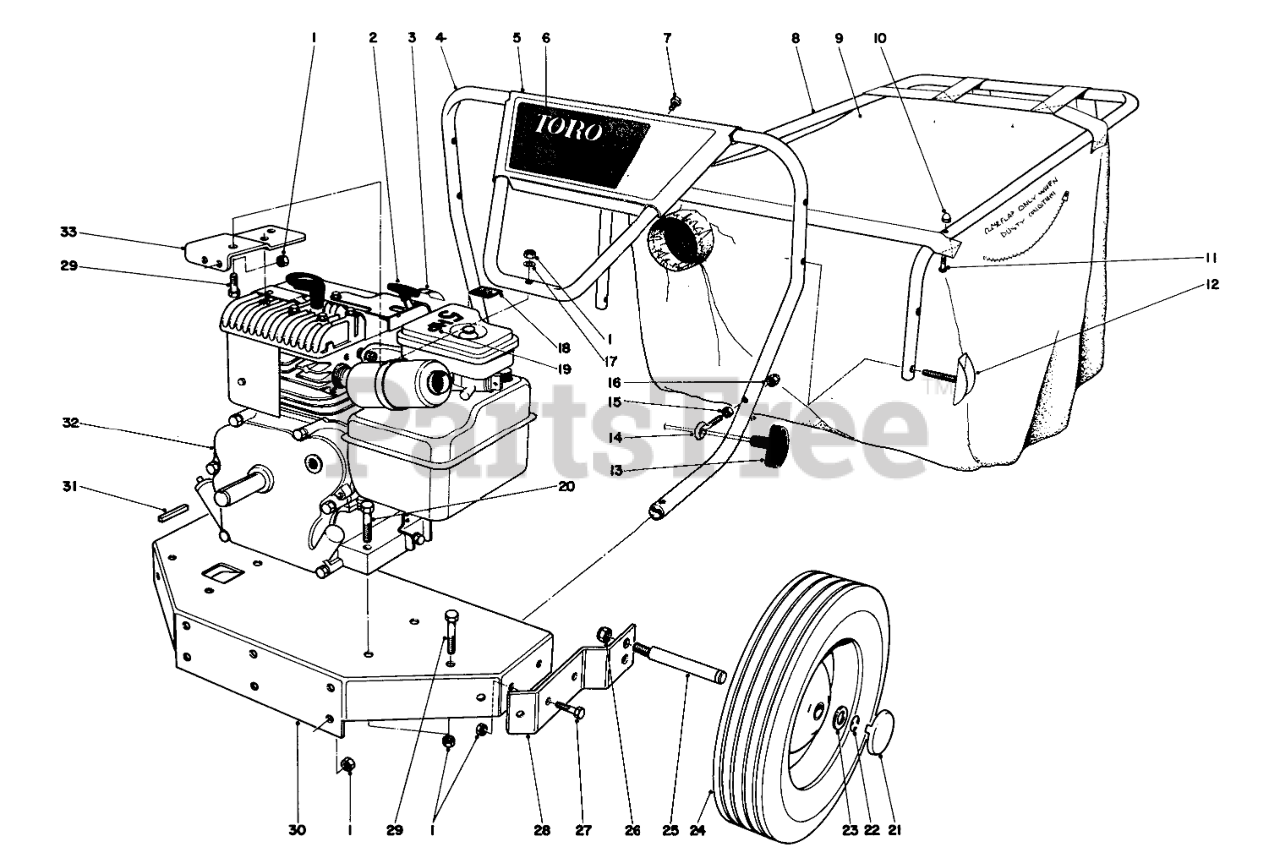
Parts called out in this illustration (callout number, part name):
1	Nut
2	Throttle Control Knob
3	Throttle Decal
4	Lower Handle
5	Handle Cover
6	Decal, Toro
7	SCREW-HH
8	Upper Handle
9	Vacuum Bag
10	Acorn Nut
11	Screw
12	Wing Bolt
13	Rubber Handle
14	Eye Bolt
15	NUT-LOCK
16	NUT-CAP
17	WASHER-LOCK
18	Caution Decal
19	Decal 5 H.P.
20	SCREW-HH
21	Hub Cap
22	Retaining Ring
23	Flat Washer
24	Rear Wheel & Tire
25	Axle, Rear
26	NUT-LOCK, NI
27	SCREW-HH
28	Rear Wheel Bracket
29	SCREW-HH
30	Engine & Wheel Mounting Plate
31	Key
32	Engine
33	Bracket
